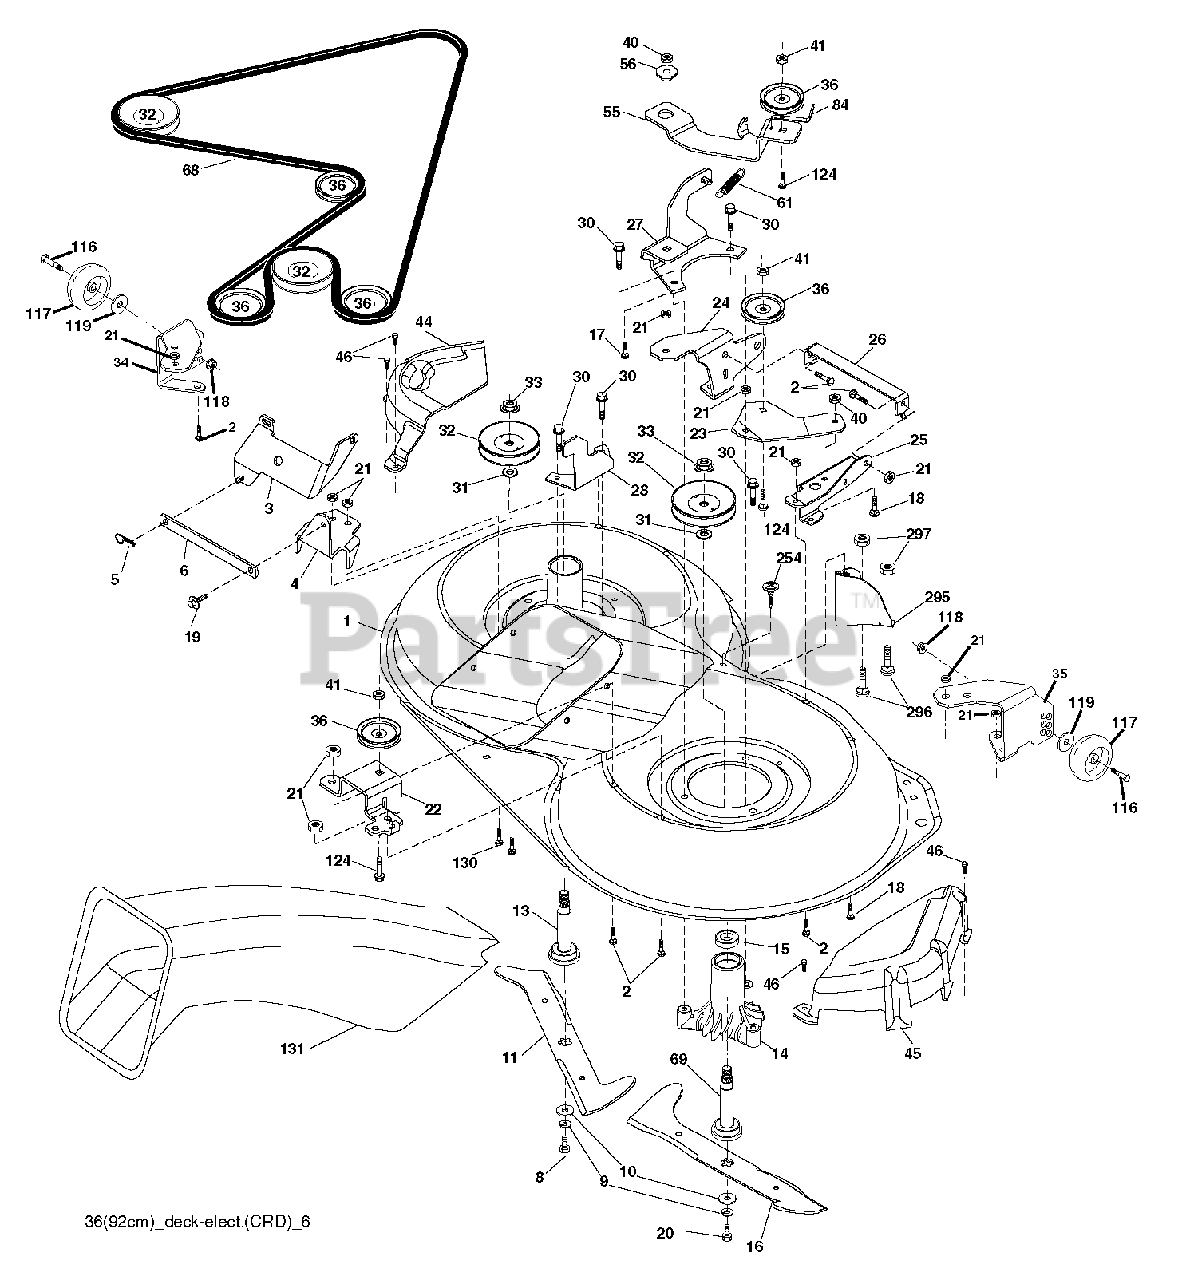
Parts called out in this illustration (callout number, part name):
2	BOLT
3	BRACKET
5	RETAINER-SPRNG RB
6	BAR SWAY
9	LOCKWASHER
10	WASHER.BLADE
13	SHAFT ASM VENT
14	HSG MANDREL
17	BOLT.3/8-14X1.25
19	BOLT SHD 5/16-18
21	LOCKNUT
24	BRACKET
25	BRACKET
28	BRACKET
30	SCREW, WASHER HEAD
31	WASHER.SPACER.MANDREL
32	PULLEY MANDREL
33	NUT.FLANGE.LOCK.TOP
36	PULLEY.IDLER.4.25
40	LOCKNUT
41	NUT LOCK FLG 3/8-16 UNC
45	MANDREL COVER
46	SCREW.1/4-20X5/8
56	SPACER.RETAINER.MOWER
69	SHAFT.ASM.W/LWR.BRG.RH.THREAD
84	KEEPER, BELT IDLER
116	BOLT.SHOULDER.3/8-16X3-5/8
117	WHEEL. GUAGE RALLY
118	NUT LOCK FLG 3/8-16 UNC
124	BOLT.3/8-16X1.50
131	CHUTE BAGGER
254	SCREW 3/8-16X1
296	BOLT
297	NUT CENTERLOCK
